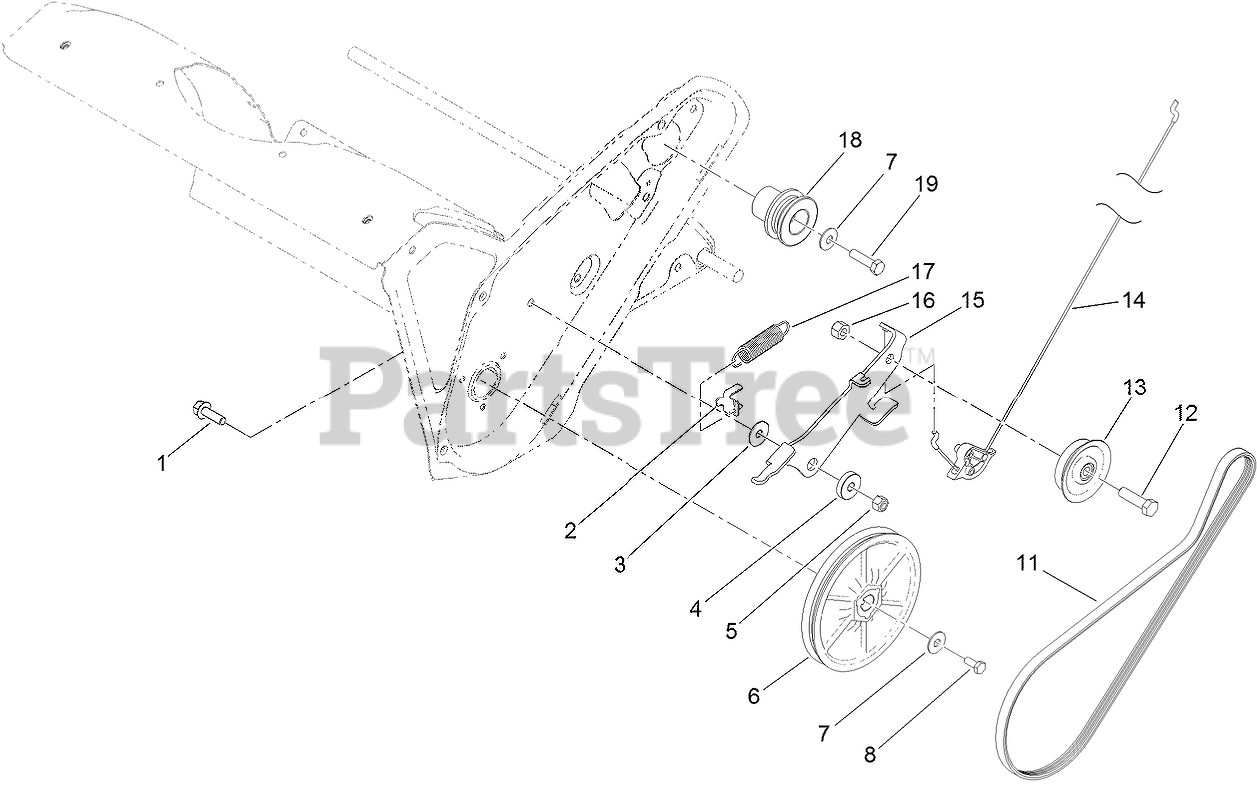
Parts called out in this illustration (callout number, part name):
1	SCREW-HHF
2	CLIP-SPRING, BRAKE
3	WASHER
4	BUSHING-PIVOT
5	NUT-LOCK, NI
6	ROTOR PULLEY ASM
7	WASHER-BELLEVILLE
8	SCREW-HH
11	BELT-DRIVE
12	SCREW-HH
13	PULLEY-IDLER
14	CABLE-CLUTCH
15	ARM-IDLER
16	NUT-LOCK, CONE
17	SPRING-EXTENSION
18	PULLEY-ENGINE
19	SCREW-HH
